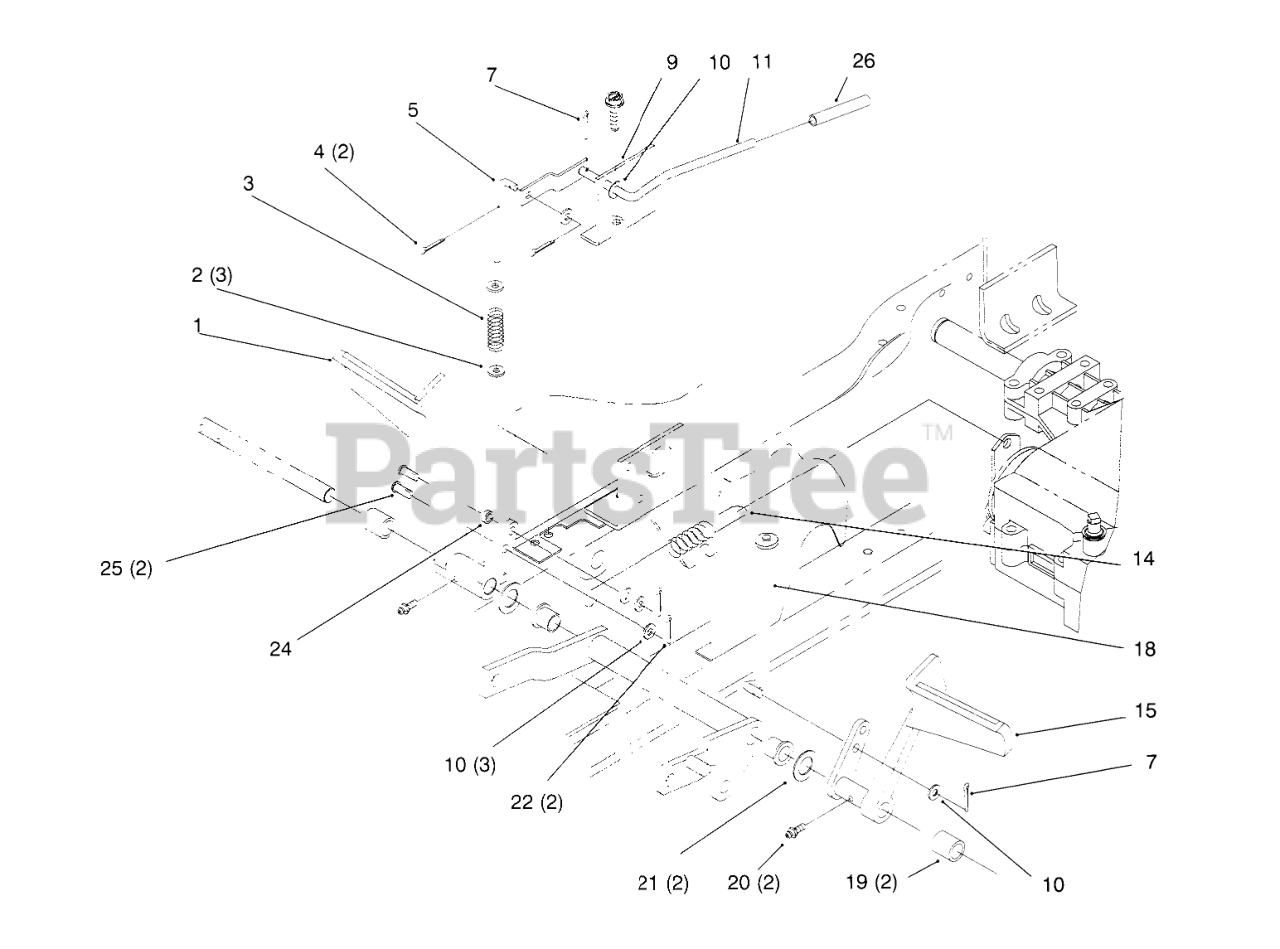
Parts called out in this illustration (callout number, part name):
1	Pedal-Brake (Only On: 72042,72062)
2	Washer-Flat (Only On: 72042,72062)
3	Spring-Compression (Only On: 72042,72062)
4	Pin-Cotter (Only On: 72042,72062)
5	Rod-Park Brake (Only On: 72042,72062)
7	Pin-Cotter (Only On: 72042,72062)
9	Bracket-Parking Brake (Only On: 72042,72062)
10	Washer-Flat (Only On: 72042,72062)
11	Lever-Parking Brake (Only On: 72042,72062)
14	Spring-Extension (Only On: 72042,72062)
15	Pedal-Clutch (Only On: 72042,72062)
18	Rod-Clutch (Only On: 72042,72062)
19	Spacer (Only On: 72042,72062)
20	Fitting-Grease (Only On: 72042,72062)
21	Washer-Wave (Only On: 72042,72062)
22	Pin-Cotter (Only On: 72042,72062)
24	Spacer (Only On: 72042,72062)
25	Pin-Clevis (Only On: 72042,72062)
26	Grip-Parking Brake (Only On 72042,72062)
